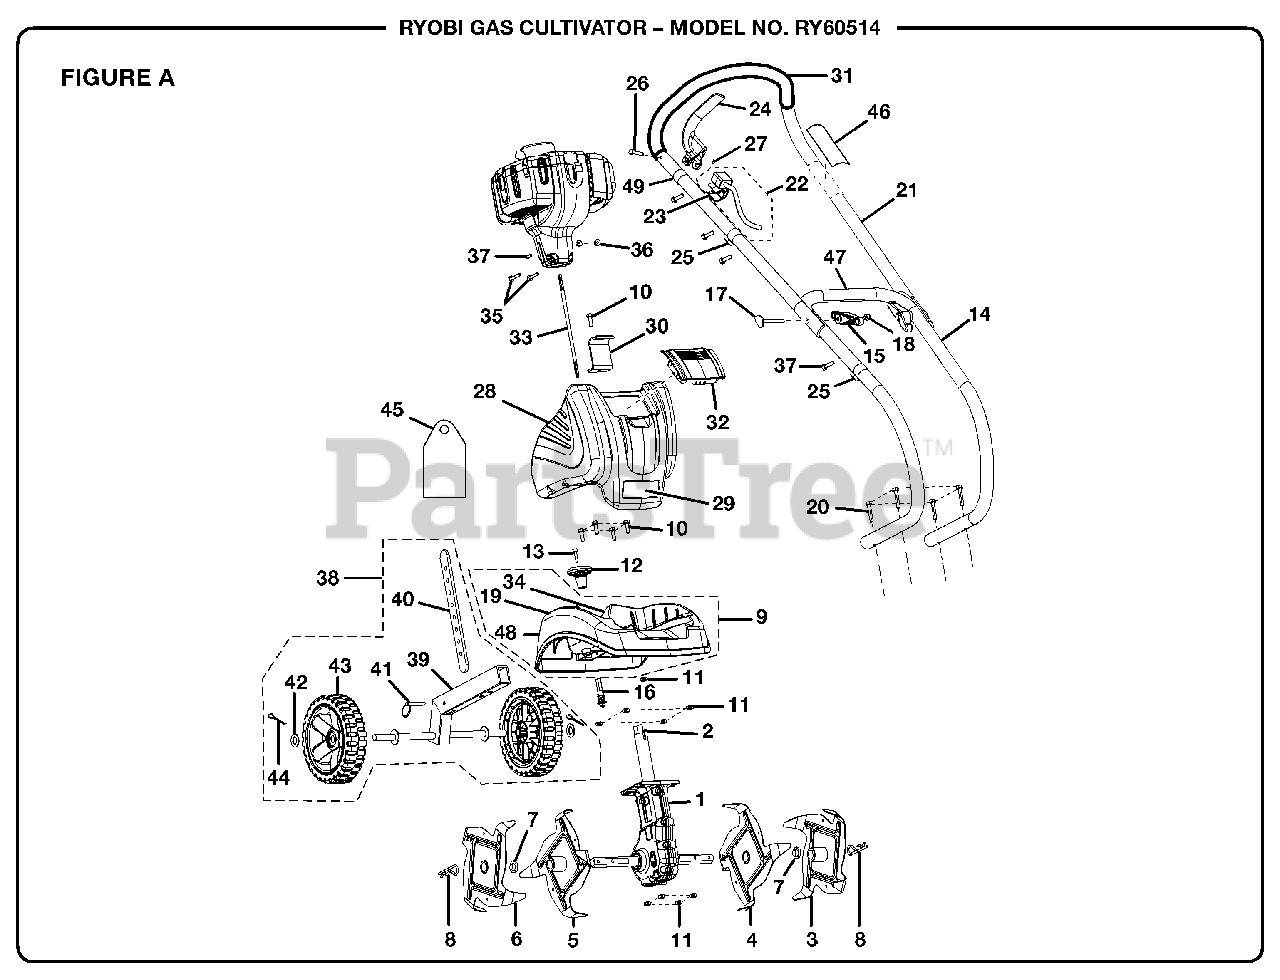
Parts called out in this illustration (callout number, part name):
1	Gear Box Assembly with Tube
2	Liner - Drive Tube
3	Tine A, Outer Right
4	Tine B, Inner Right
5	Tine C, Inner Left
6	Tine D, Outer Left
7	Felt Washer
8	Clevis Clip
9	Tine Shield Assembly
10	Bolt (1/4-20 x 1 in.)
11	Lock Nut (1/4-20)
12	Receiver Retainer Knob
13	Screw (M5 x 16 mm Pan Hd.)
14	Lower Handle Assembly
15	Knob (1/4-20)
16	Receiver Retainer Assembly
17	Carriage Bolt (1/4-20 x 2-1/4 in.)
18	Acorn Nut
19	Warning Label, Foot
20	Handle Bolt (1/4-20 x 1.53 in.)
21	Upper Handle Assembly
22	Throttle Cable Assembly
25	Plastic Clip
26	Clevis Pin
27	Retaining Ring
28	Tank - Ballast Assembly
29	Logo Label
30	Mounting Bracket
32	Ballast Tank Lid
33	Flexible Drive Shaft
34	Wheel Accessory Label
35	Bolt (10-24 x 1-1/4 in.)
36	Lock Nut (10-24)
37	Screw (8-16 x 1/2 in.)
38	Wheel/Drag Stake Assembly
39	Frame Assembly
40	Drag Stake
41	Quick Release Pin
43	Wheel Assembly (6 in. Dia.)
44	Cotter Pin
45	Warning Hang Tag
46	Boom Warning Label
47	Starting Label
48	Warning Label
49	Rope Clip
